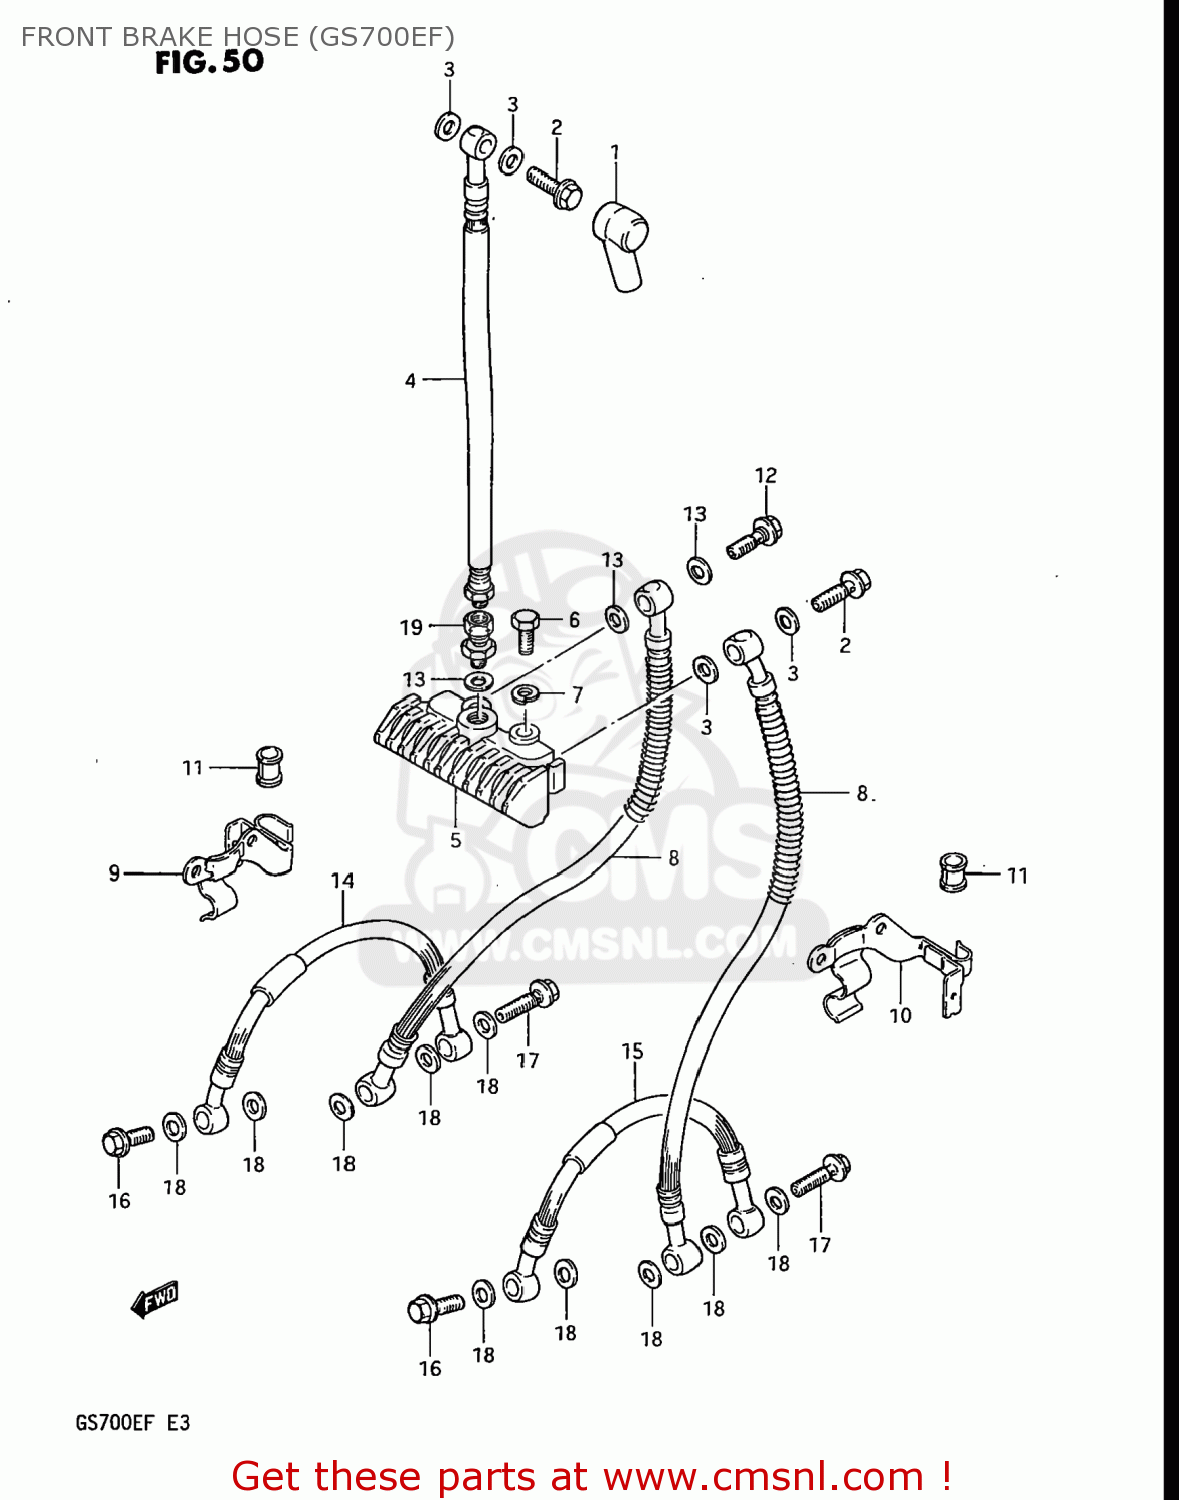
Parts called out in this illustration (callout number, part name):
1	BOOT
2	BOLT UNION
3	WASHER(10X15X1.5)
4	HOSE,FRONT BRAKE NO.1
5	JOINT,BRAKE HOSE
6	BOLT
7	LOCK WASHER
8	HOSE,FRONT BRAKE
9	CLAMP,FRONT BRAKE HOSE
10	CLAMP,BRAKE HOSE,LEFT
11	BUSH,BRAKE HOSE GUIDE,NO.2
12	BOLT UNION
13	WASHER(10X15X1.5)
14	HOSE,ANTI-NOSE DIVE
15	HOSE,ANTI-NOSE DIVE
16	BOLT UNION
17	BOLT UNION
18	WASHER(10X15X1.5)
19	ADAPTER,BRAKE HOSE
